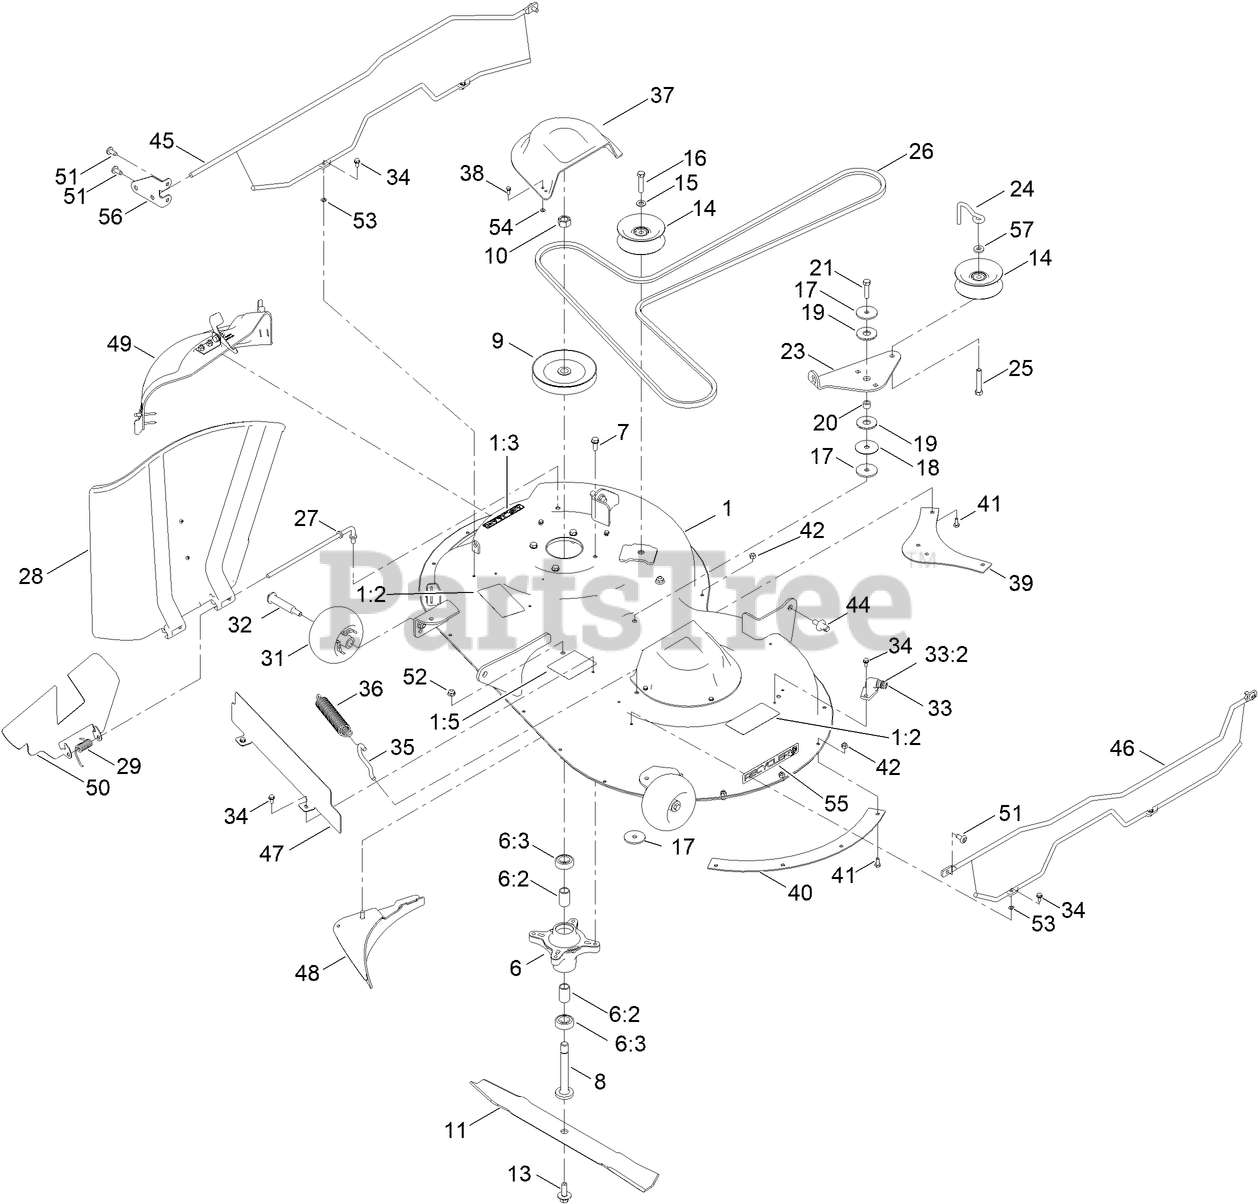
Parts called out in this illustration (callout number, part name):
1	42 INCH DECK AND DECAL ASM
1:2	DECAL-DANGER, DECK
1:3	DECAL-DANGER
1:5	DECAL-ROUTING, BELT
6	SPINDLE ASM
6:2	SPACER
6:3	BEARING-BALL
7	SCREW-TAPTITE
8	SHAFT-SPINDLE
9	Pulley
10	Nut-Hex
11	BLADE-MULCH
13	BOLT-BLADE, SEMS
14	PULLEY-IDLER, FLAT
15	WASHER-FLAT
16	SCREW-HH
17	Washer
18	WASHER
19	WASHER-FRICTION, COMPOSITE
20	SPACER
21	SCREW-HH
23	ARM-IDLER
24	BELT GUIDE - IDLER
25	SCREW-HH
26	V-BELT
27	ROD-PIVOT
28	DEFLECTOR
29	SPRING-TORSION
31	ROLLER-SCALP, ANTI
32	BOLT-SHOULDER
33	FITTING-WASHOUT
33:2	O-RING
34	SCREW-HWH
35	HOOK-RETURN SPRING
36	SPRING-EXTENSION
37	COVER-BELT
38	SCREW-TAPTITE
39	BAFFLE-BLOWOUT, REAR
40	BAFFLE-BLOWOUT, SIDE
41	SCREW-HH
42	NUT-HEX
44	PIN-DECK
45	LEFT GUARD ASM
46	RIGHT GUARD ASM
47	SHIELD-FROUNT
48	BAFFLE-CLIPPING
49	42 INCH MULCH PLUG ASM
50	DEFLECTOR-INSERT
52	NUT-HF
53	NUT-RETAINING
54	NUT-RETAINING
55	DECAL-RECYCLER
56	PLATE-MOUNT, GUARD
57	SPACER-HUB, BLOWER
